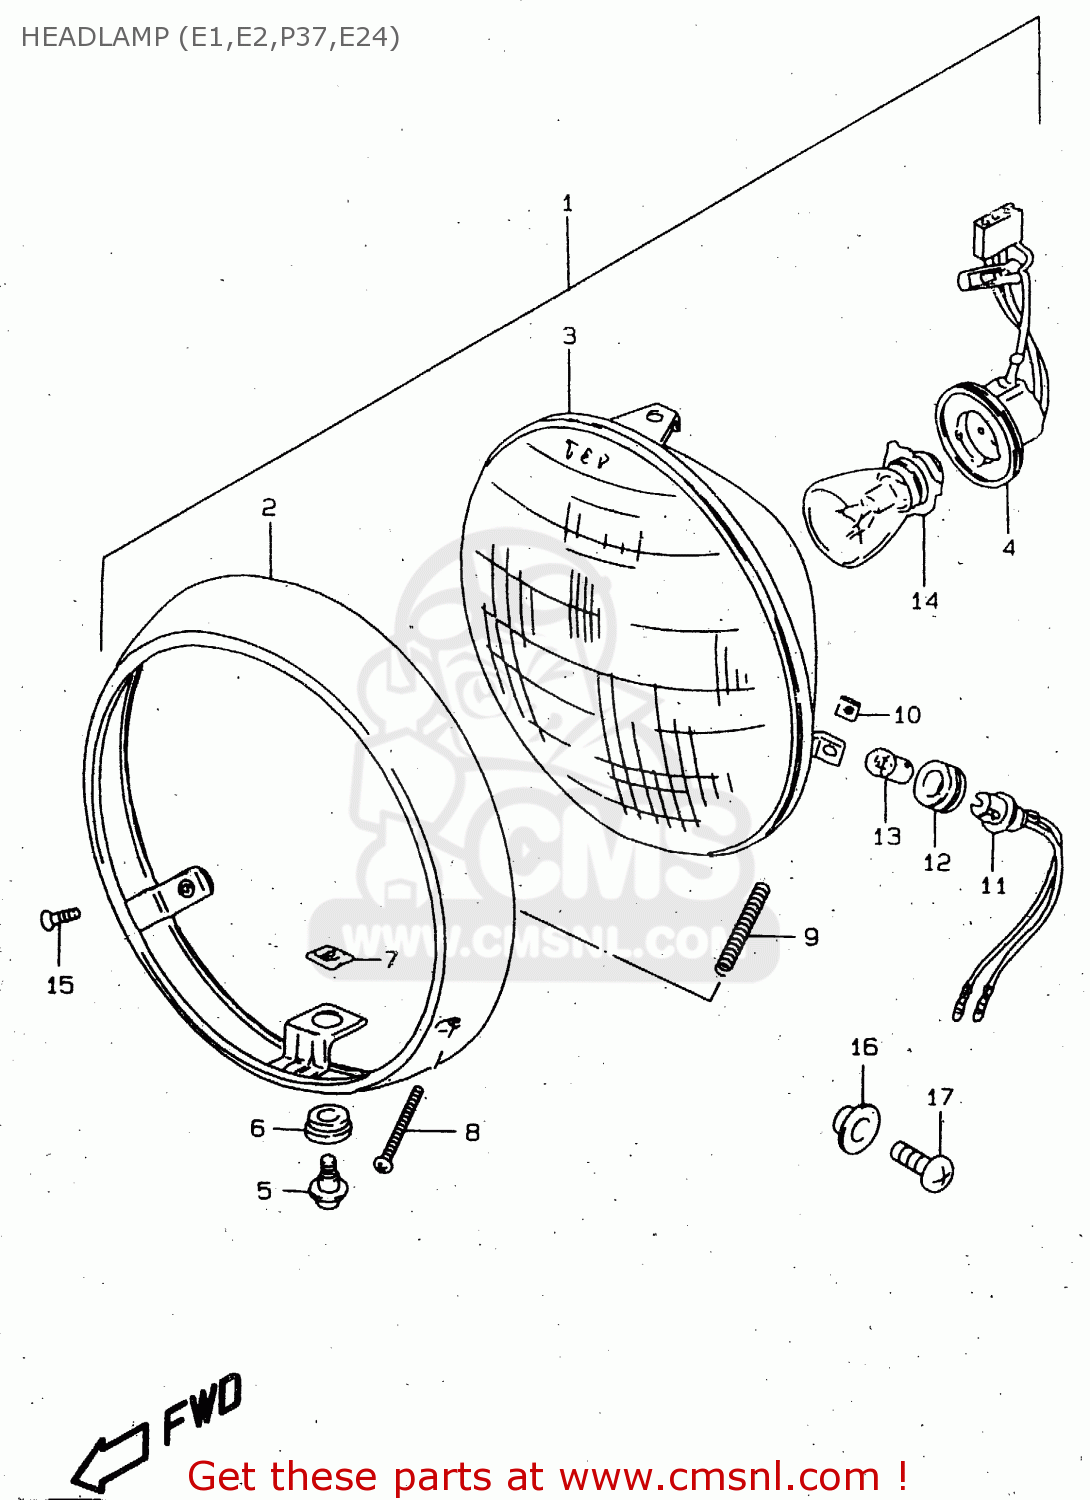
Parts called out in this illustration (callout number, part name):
1	HEADLAMP ASSY
2	RIM
3	LAMP UNIT
4	COVER,SOCKET
5	SCREW,MOUNTING
6	CUSHION
7	NUT
8	SCREW
9	SPRING
10	NUT
11	SOCKET
12	JOINT,RUBBER
13	BULB(12V4W)
14	BULB
15	SCREW
16	WASHER
17	SCREW
